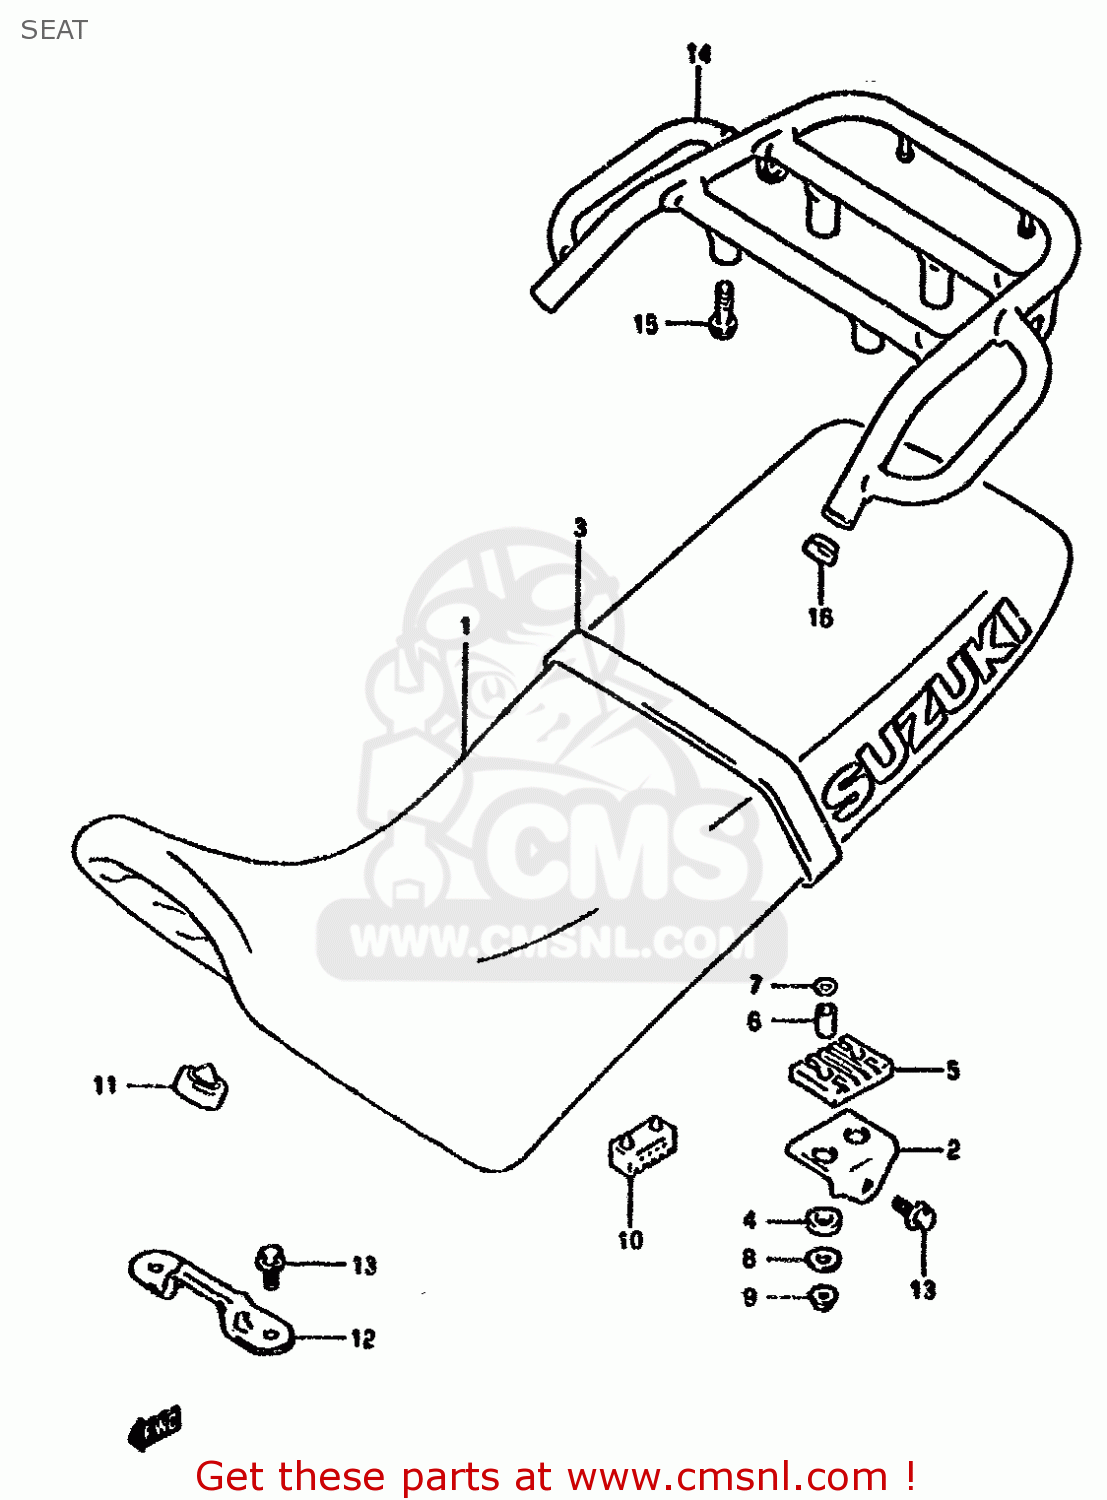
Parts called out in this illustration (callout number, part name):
1	SEAT SET
2	BRACKET,SEAT
3	BAND,SEAT
4	CUSHION,SEAT FR
5	CUSHION,FR PLATE
6	SPACER,SEAT BRACKET
7	WASHER
8	WASHER
9	NUT
10	CUSHION,SEAT(40X20X15)
11	CUSHION,FRONT
12	PLATE,SEAT FR HOOK
13	BOLT, 8X1.25X1
14	CARRIER,SPORT
15	BOLT 6X16
16	CAP(OD:19)
